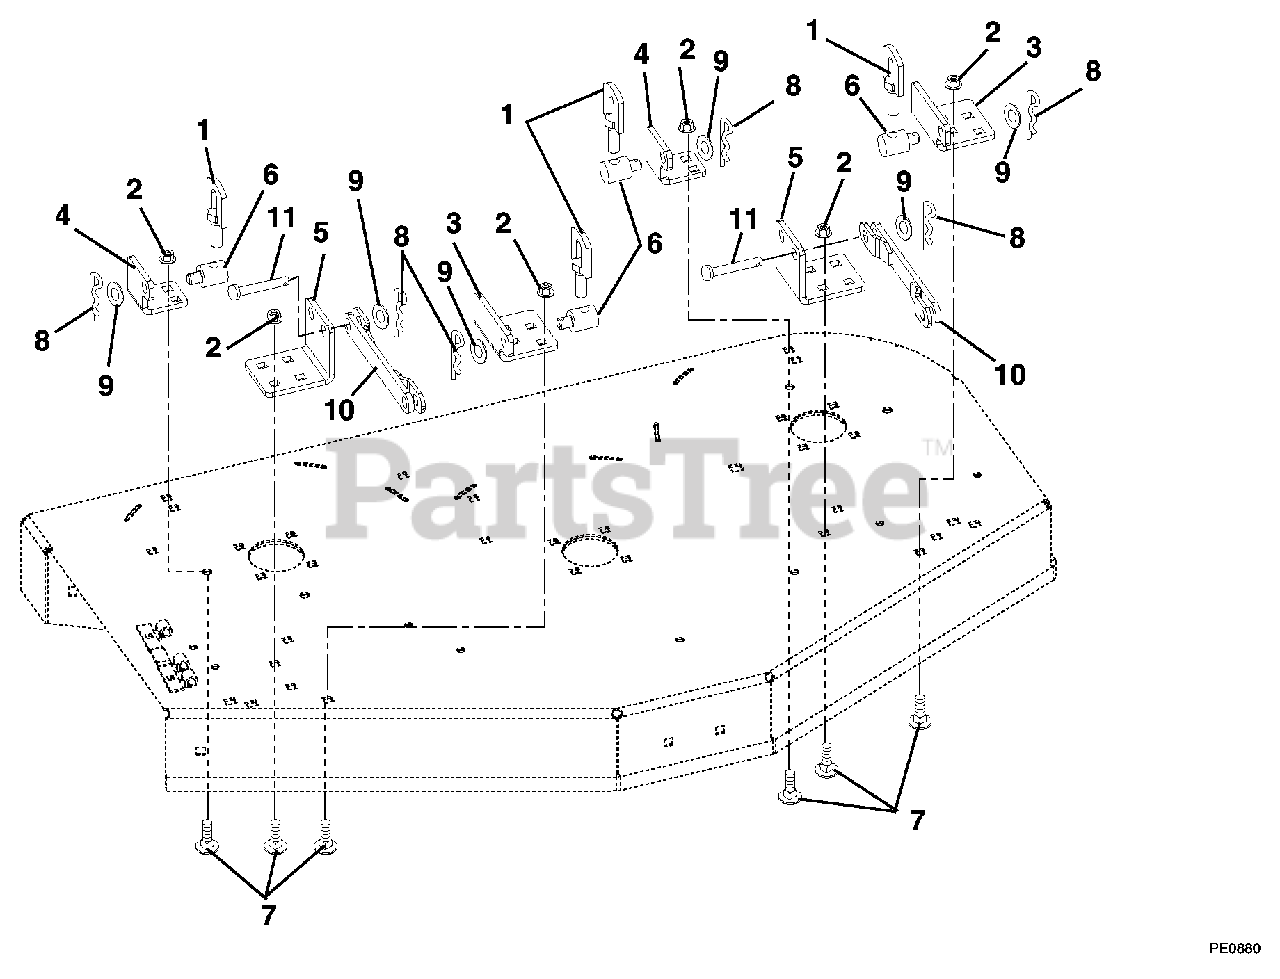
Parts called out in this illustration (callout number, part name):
1	Weldment, Adjustment Link
2	Nut, Locking Top Flange .38-16
3	Bracket, Mount, Front
4	Bracket, Rear Mount
5	Bracket, Stabilizer
6	Trunnion
7	Bolt, Round Head Square Neck .38-16 x .75 Grade 5
8	Pin, Hair, External
9	Washer, Flat Steel .51 x 1.44 x .125
10	Weldment, Stabilizer Arm
11	Clevis Pin, .491/.496 x 1.25
